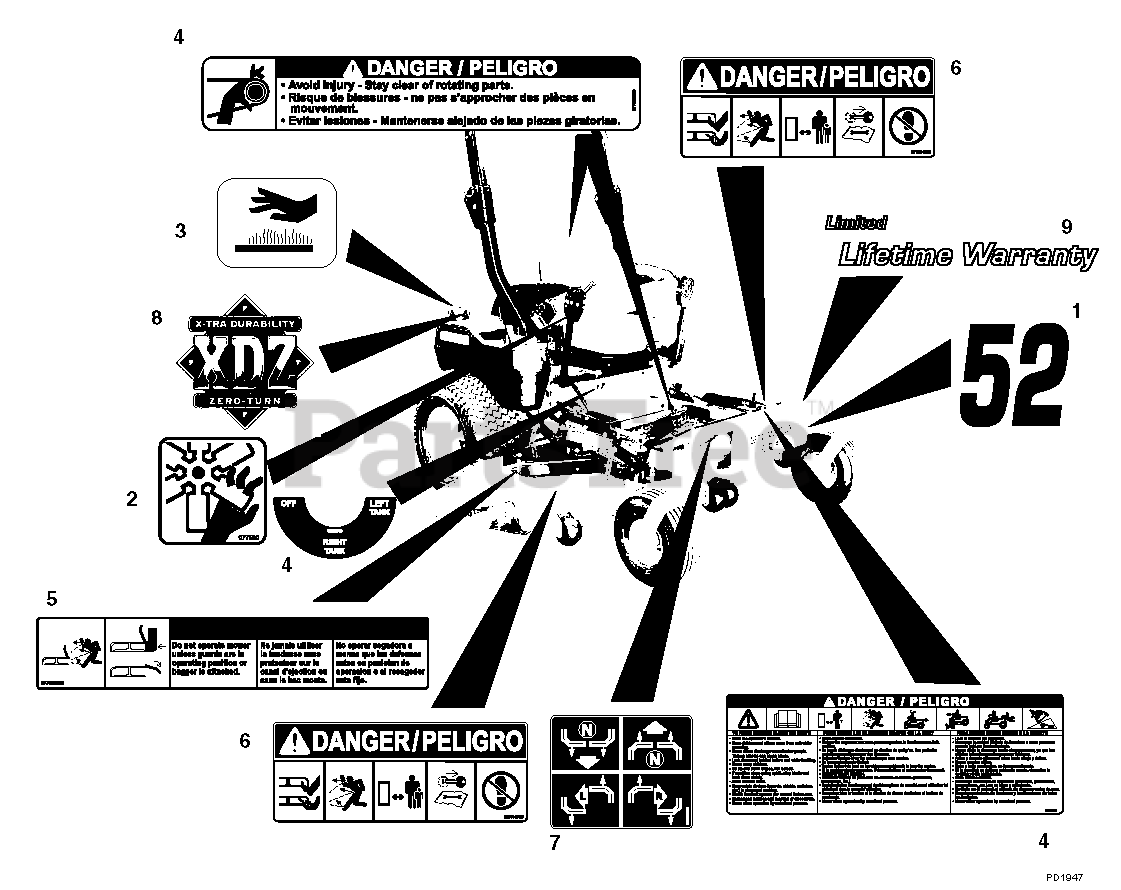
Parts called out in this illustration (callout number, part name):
1	Decal, 52
1	Decal, 60
1	Decal, 66
1	Decal, 72
2	Decal, Danger Fan
3	Decal, Hot Surface
4	Set, Decal - Common Danger/Fuel
5	Decal, Warning
6	Decal, Mower Pan Head Danger
7	Decal, Maintenance Instructions
8	Decal, XDZ
9	Decal, Limited Lifetime Warranty
